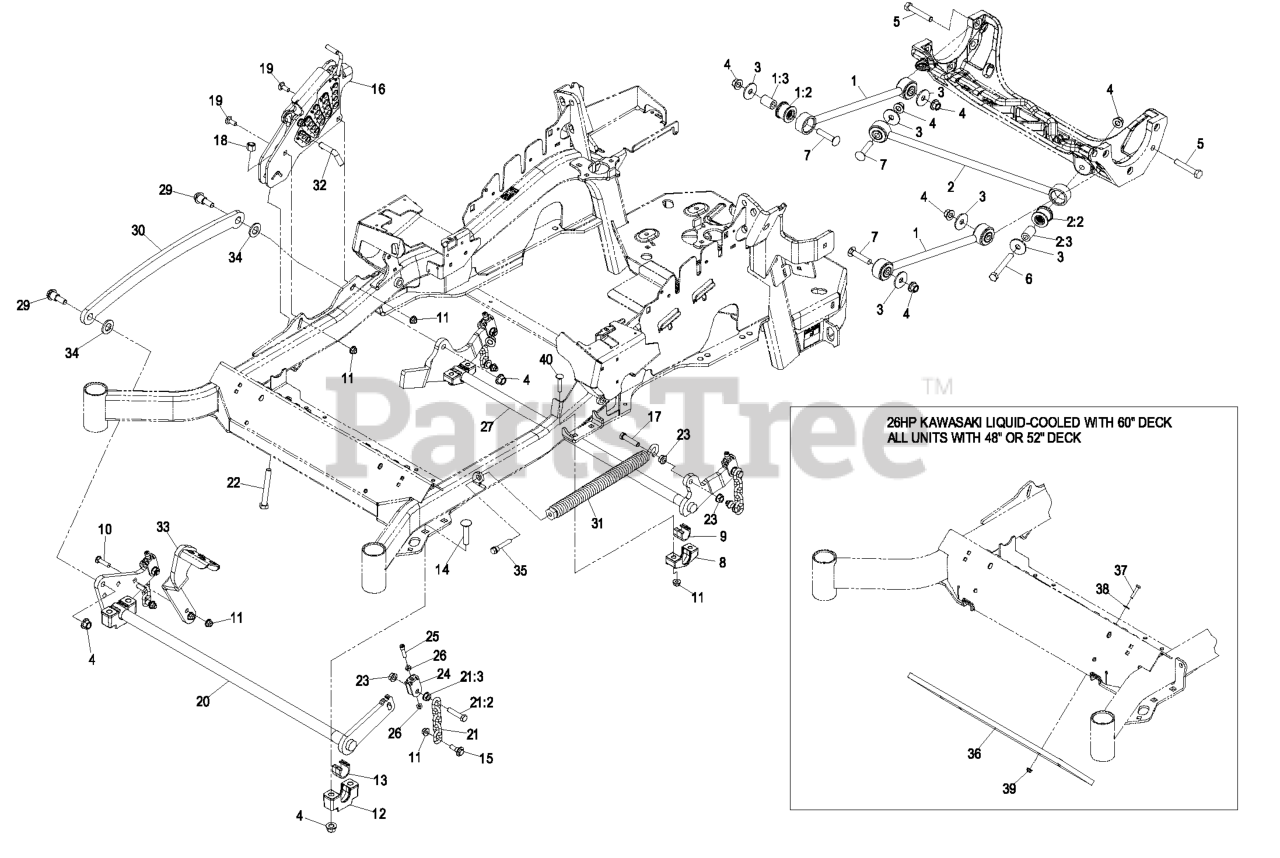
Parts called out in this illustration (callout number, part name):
1	DECK STRUT ASM
1:2	BUSHING-SUSPENSION, RUBBER
2	PANHARD ROD ASM
2:2	BUSHING-SUSPENSION, RUBBER
3	WASHER-THRUST
4	Nut-Lock 1/2-13
5	SCREW-HH
6	SCREW-HH
7	SCREW-CARR
9	BEARING-CROSS SHAFT, REAR
10	SCREW-CARR
11	NUT-HF, NI
12	SUPPORT-CROSS SHAFT, BEARING
13	BEARING-CROSS SHAFT, FRON
14	Bolt-Carriage 1/2-13 X 2 1/2 Spl Neck
15	SCREW-SHOULDER, HHF
16	HOC ASM
17	SCREW-HH
18	NUT-LOCK, NI
19	BOLT-CARR
21	Deck Lift Chain Asm
21:2	SCREW-HH
22	BOLT-TAP
24	YOKE-ADJUST, DECK
25	SCREW-HSH
26	NUT-JAM
27	LIFT-DECK, REAR
29	SCREW-SHOULDER, HHF 1/2-13 X 1.12
30	LINK-LIFT, DECK
31	SPRING-EXTENSION
32	PIN-HOC
33	LEVER-FOOT
34	WASHER-FLAT
35	BOLT-SHOULDER
36	WEIGHT,TOE BOARD
37	SCREW-HH
38	WASHER-FLAT
40	SCREW-CARR
